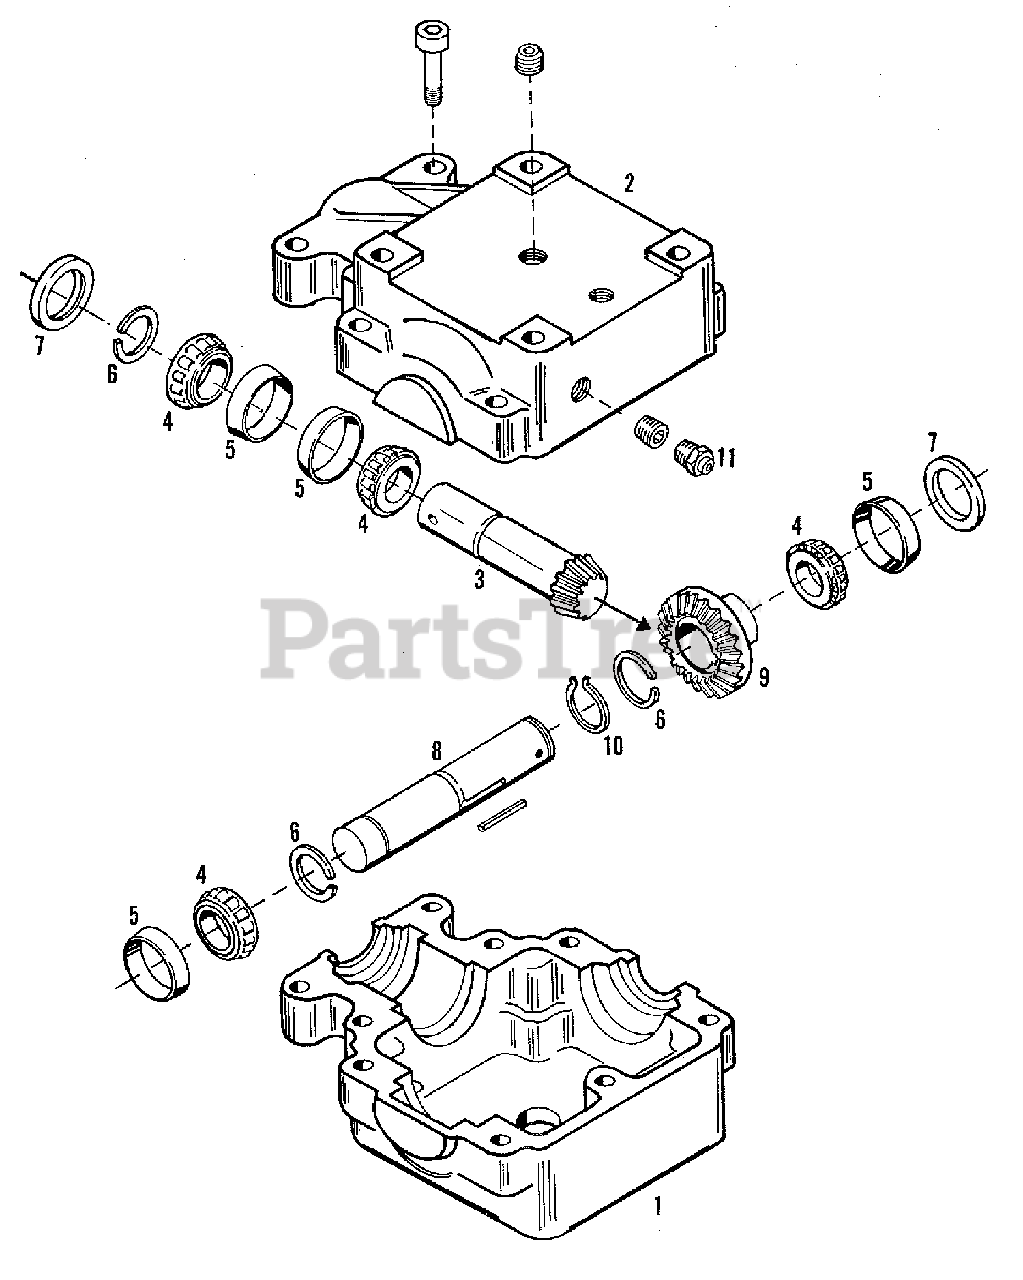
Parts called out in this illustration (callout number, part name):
1	HOUSING, Half (Threaded Holes)
1	PLUG, Pipe, 1/2
2	HOUSING, Half (Thru Holes)
2	CAPSCREW, Socket Head, 3/8NC x 2
2	PLUG, Pipe, 1/2
2	BUSHING, Pipe, 1/2 x 1/8
3	SHAFT, Pinion
4	CONE, Bearing
5	CUP, Bearing
6	RING, Retaining
8	SHAFT, Cross
10	RING, Retaining
11	PLUG, Pressure Relief
